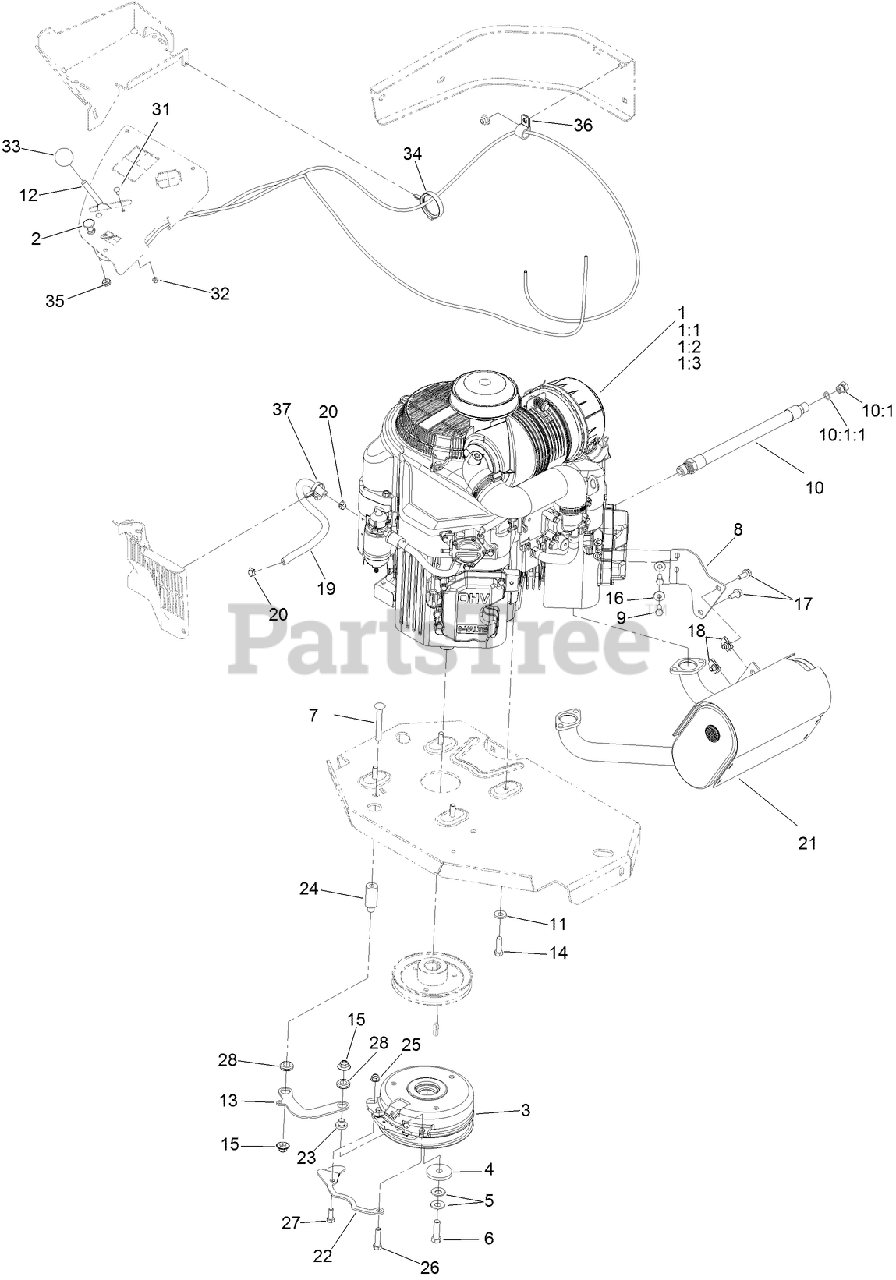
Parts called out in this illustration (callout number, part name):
1:1	KAWASAKI 49065-7007 ENGINE OIL FILTER
1:2	KAWASAKI 11013-7044 ENGINE AIR FILTER
1:3	KAWASAKI 11013-7045 SAFETY FILTER
2	CABLE-CHOKE
3	CLUTCH KIT
4	WASHER-CLUTCH
5	WASHER-SPRING
6	SCREW-HH, W/LOCTITE
7	SCREW-CARR
8	BRACKET-MUFFLER
9	SCREW-HH
10	ENGINE OIL DRAIN HOSE ASM
10:1	PLUG-HH
10:1:1	O-RING
11	WASHER-BELLEVILLE
12	THROTTLE-CONTROL
13	LINK-ANCHOR, CLUTCH
14	SCREW-HH
15	NUT-FLANGE, NI
16	WASHER-SPRING
17	SCREW-HHF
18	NUT-U
19	HOSE-FUEL
20	CLAMP-HOSE
21	MUFFLER
22	BELT-GUIDE
23	SPACER
24	SPACER
25	NUT-HF, NI
26	SCREW-HH
27	SCREW-HH
28	GROMMET-RUBBER
31	BOLT-CARR
32	NUT-LOCK, NI
33	KNOB-BALL
34	CLAMP-HARNESS
35	NUT-HJ
36	CLIP-LOOM
37	CLAMP-HOSE
